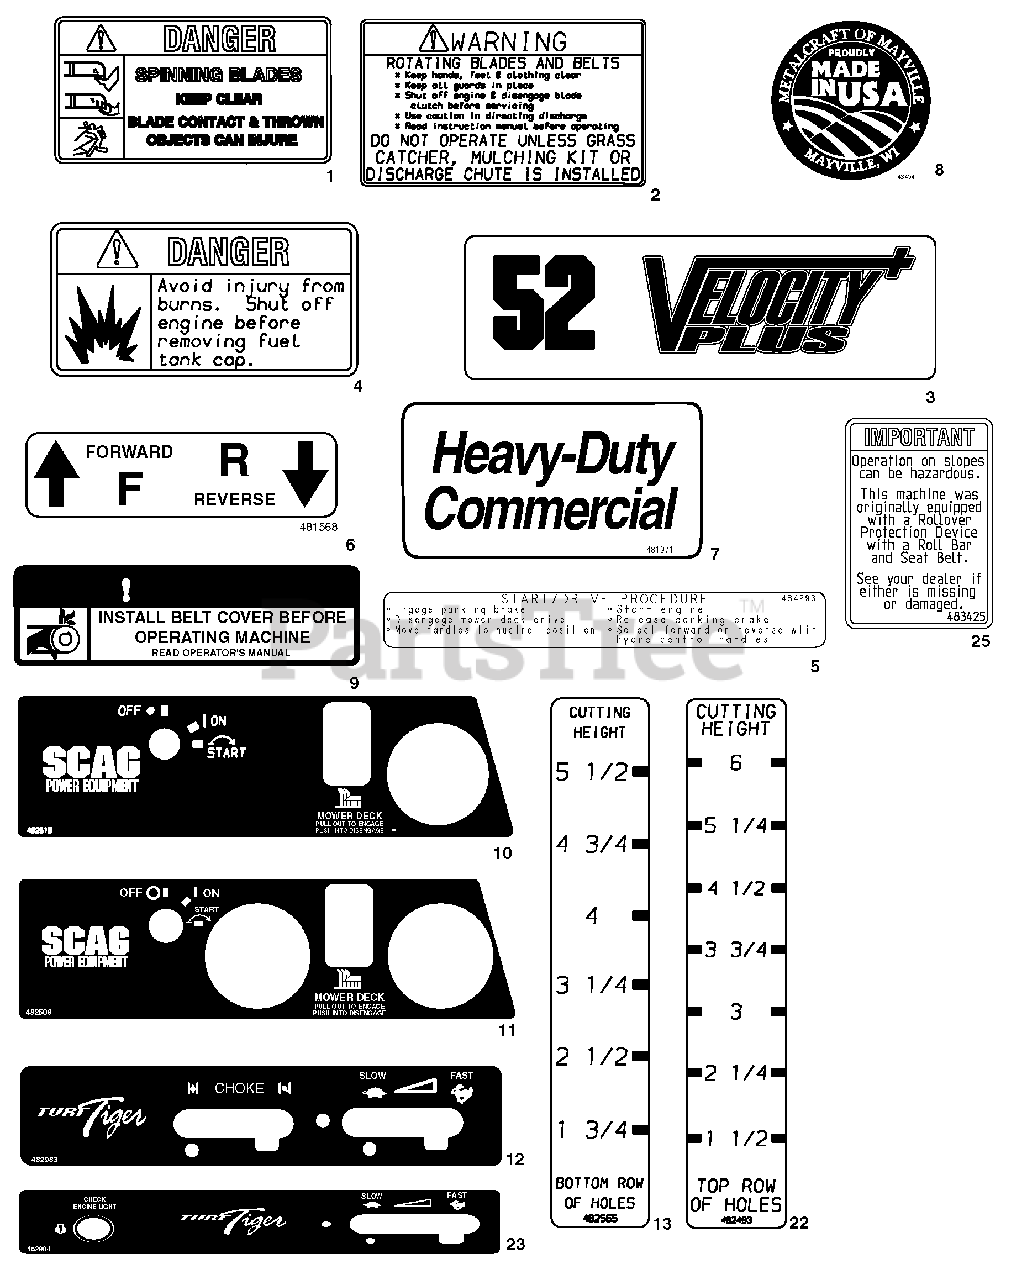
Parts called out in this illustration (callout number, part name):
1	Decal, Danger - Spinning Blades
2	Decal, Warning - Rotating Blades
3	Decal, 52 Velocity Plus
3	Decal, 61 Velocity Plus
3	Decal, 72 Advantage
3	Decal, 72 Velocity Plus
4	Decal, Fuel Tank
5	Decal, Start / Drive
6	Decal, Traction Control
7	Decal, Heavy-Duty Commercial
8	Decal, Metalcraft-Made In USA
9	Decal, Belt Cover
10	Decal, Instrument Panel - Upper (Air-Cooled)
11	Decal, Instrument Panel - Upper (Kawasaki)
12	Decal, Instrument Panel-Lower
13	Decal, Cutting Height - Lower
22	Decal, Cutting Height - Upper
23	Decal, Instrument Panel - Lower (DFI & EFI only)
25	Decal, ROPS
